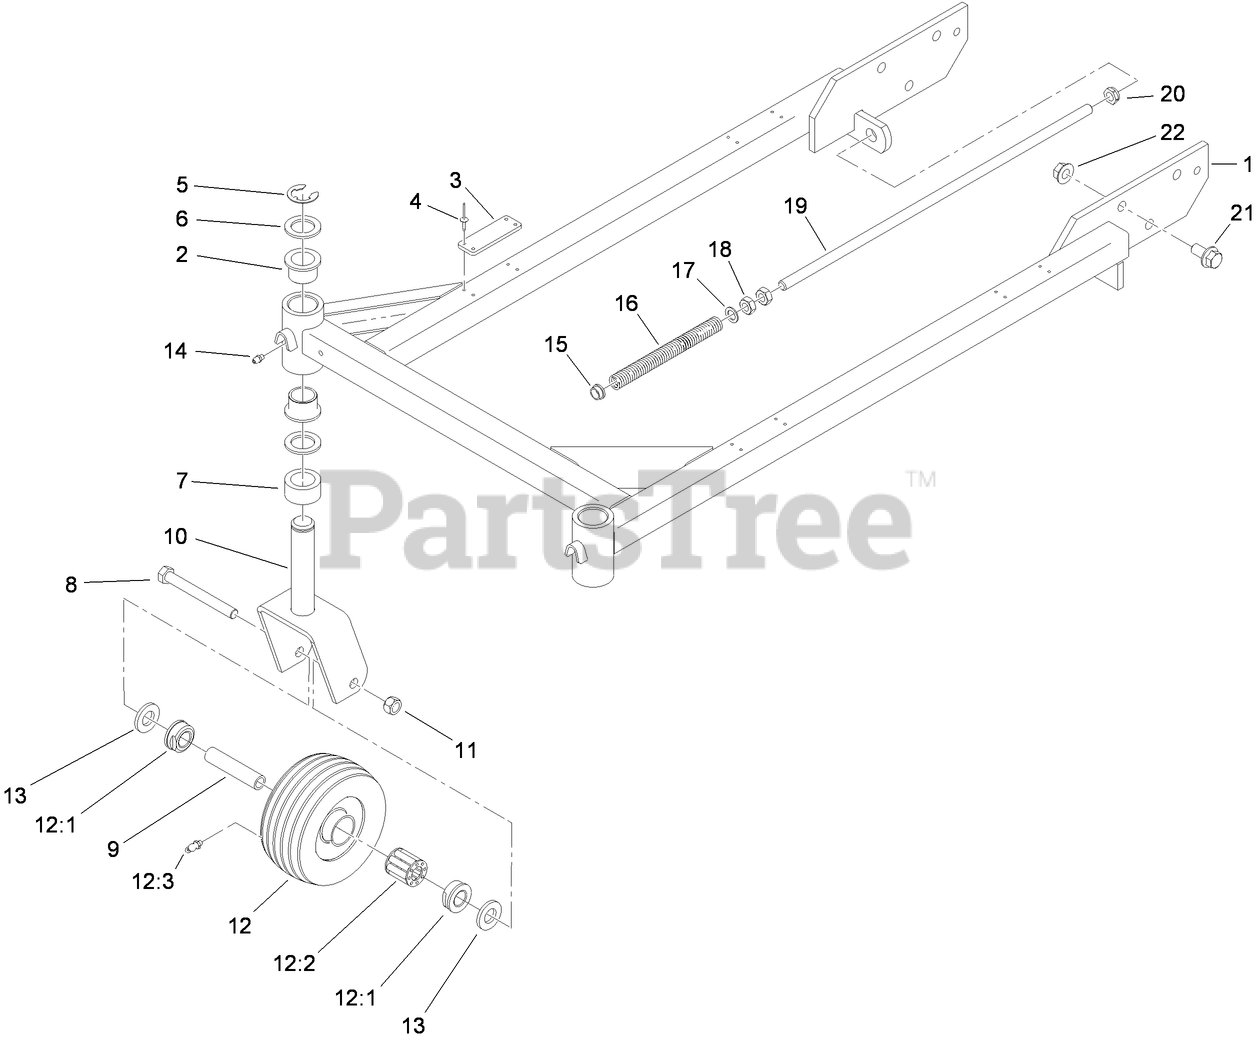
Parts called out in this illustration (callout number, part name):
1	CARRIER FRAME ASM
2	BUSHING
3	PAD-RUBBER
4	RIVET
5	RING-SNAP
6	WASHER-THRUST
7	SPACER-CASTOR
8	SCREW-HH
9	SPANNER
10	FORK-CASTER ASM
11	NUT-HEX
12	CASTER WHEEL ASM
12:1	BEARING-OUTSIDE
12:2	BEARING-ROLLER
12:3	FITTING-GREASE, 90 DEG
13	SPACER-WHEEL
14	FITTING-GREASE
15	BUSHING-FLANGE
16	SPRING
17	WASHER
18	NUT-JAM
19	SHAFT-ADJUSTING
20	NUT-LOCK, NI
21	SCREW-HHF
22	NUT-HF
